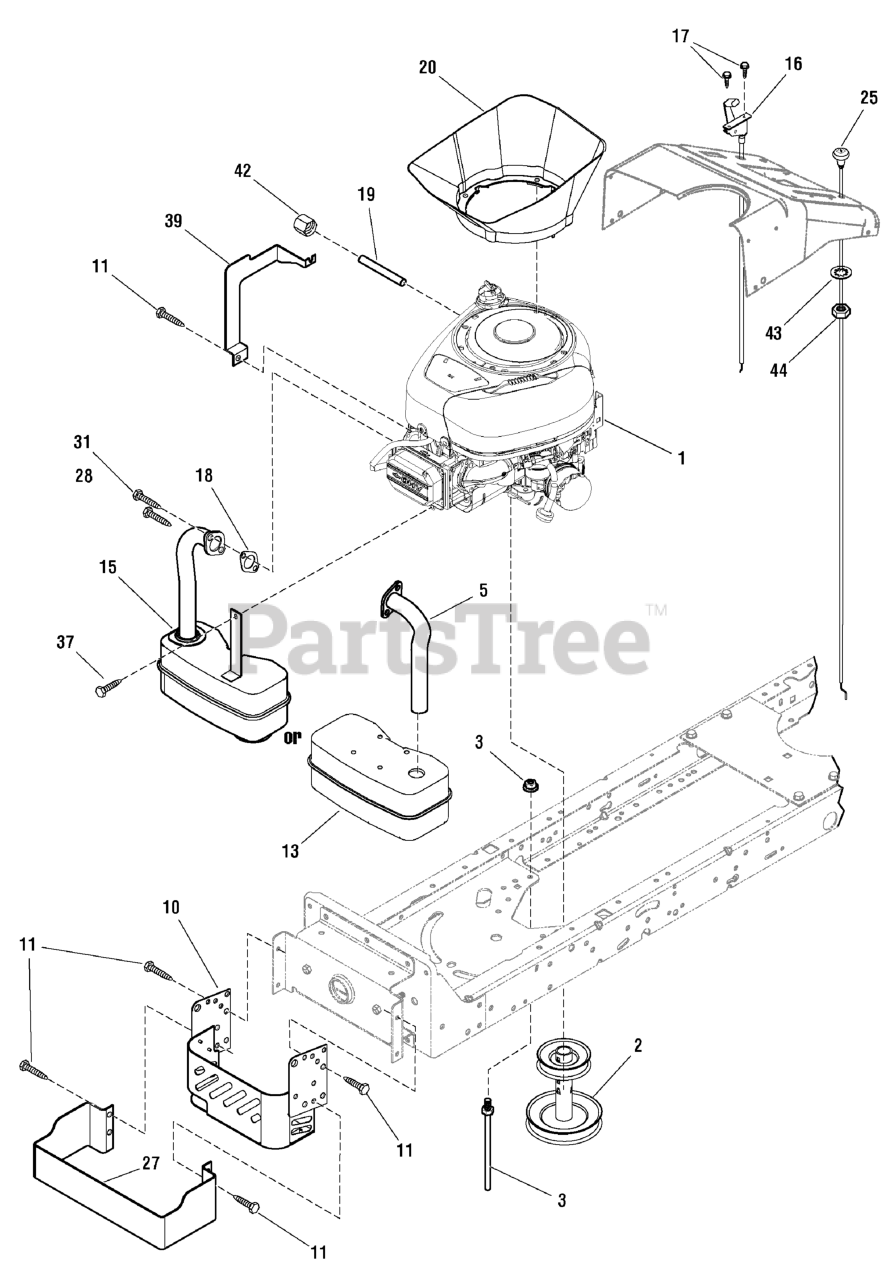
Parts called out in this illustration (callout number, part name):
1	* ENGINE, 12.5HP Briggs & Stratton
1	* ENGINE, 15.5HP Briggs & Stratton
1	* ENGINE, 17.5HP Briggs & Stratton
2	PULLEY, Stack
3	GUIDE, Belt
4	NUT, Flange, 5/16-18
5	EXHAUST TUBE, Single
10	HEAT SHIELD
11	SCREW, Hex Head, 5/16-18 x 5/8
13	MUFFLER, Single
15	MUFFLER ASSEMBLY, Single
16	THROTTLE CONTROL
17	SCREW, Self Tap #8 x 3/8
18	GASKET, Exhaust
19	NIPPLE, Pipe, 3/8 x 3 in
20	PLENUM, Murray
25	CABLE, Choke
27	GUARD, Heat Shield, Front
28	SCREW, Torx Head, 5/16-18 x 3/4
31	SCREW, 5/16-18 x 3/4
37	SCREW, Thread Forming, 1/4-20 x 5/8
39	GUARD, Exhaust Pipe
42	CAP, Pipe, 3/8
43	WASHER, Star
44	NUT, Hex, 3/8-16
